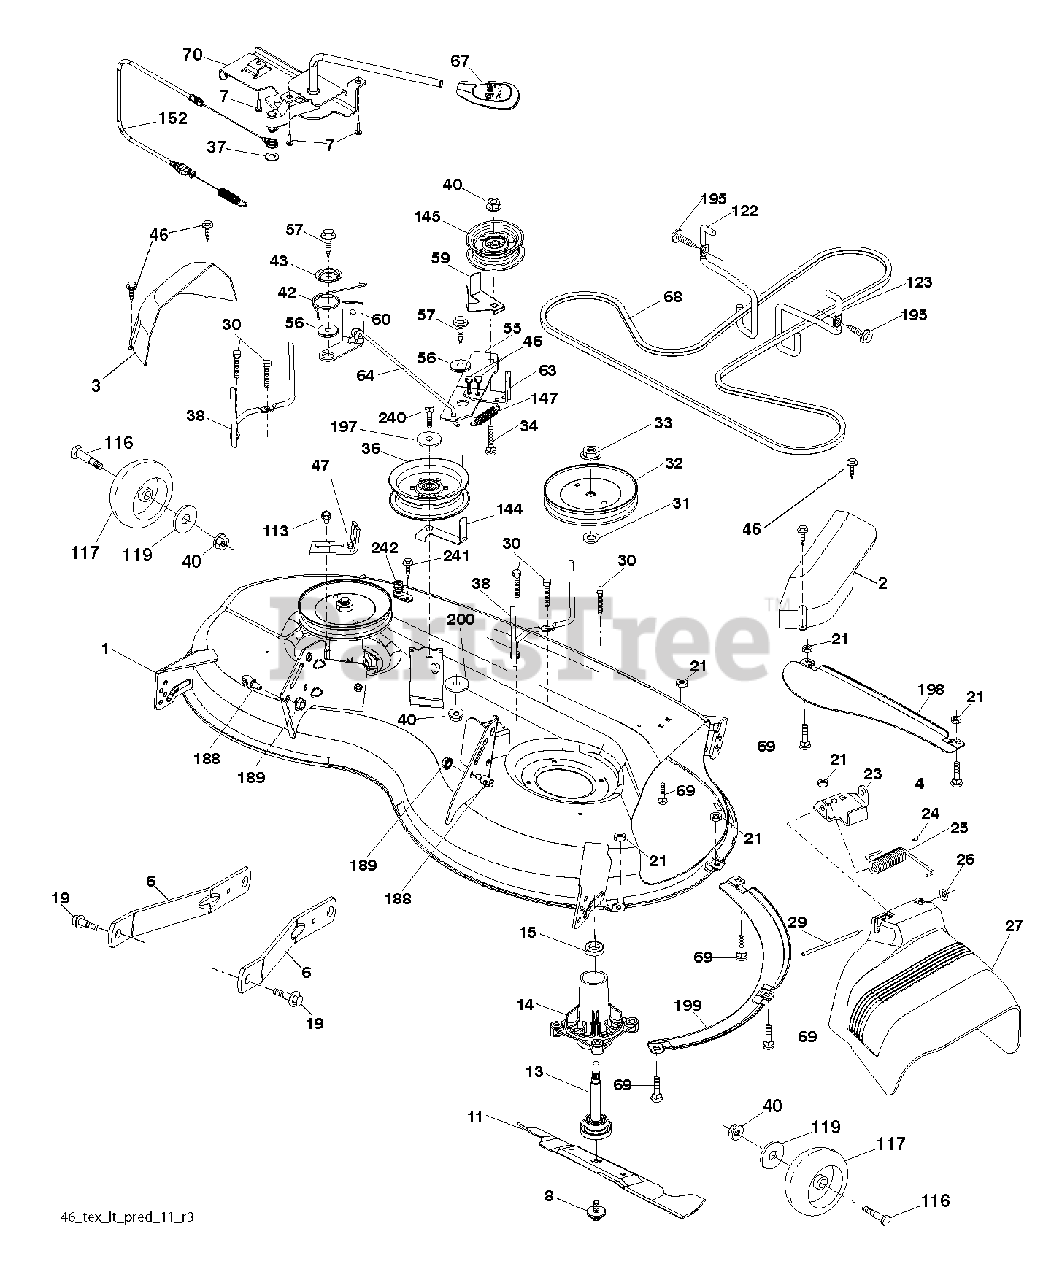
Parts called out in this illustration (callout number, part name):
1	DECK.WELDMENT.46.2GA.WHLS.GRAY
2	COVER.MANDREL.RH.46"
3	COVER.MANDREL.LH.46"
4	BOLT
6	ARM.SUSPENSION.MOWER.R
7	SCREW.#10 X 0.750.BOS
8	BOLT.WASHER.ASM.7/16-2
11	BLADE.MOWER.46".HI.LIFT
13	SHAFT.ASM.MDRL.N/GREASE.38
14	HOUSING.MANDREL.4PT.
19	BOLT.SHOULDER
21	LOCKNUT
23	BRKT.DEFLECTOR.38"2005+
24	CAP-SLEEVE LT
25	SPRING.TORSION.DEFLECT
26	NUT PUSH M
27	SHIELD.DEFLECTOR.MOWER.46"BLAC
29	ROD.HINGE
30	SCREW, WASHER HEAD
31	WASHER.SPACER.MANDREL
32	PULLEY.MANDREL.5.438.PD
33	NUT.FLANGE.LOCK.TOP
34	BOLT.3/8-16X1.50
36	PULLEY.IDLER.2006
37	WASHER
38	KEEPER.BELT.MANDREL.PULLEY
40	NUT LOCK FLG 3/8-16 UNC
42	SPRING.TORSION.BRAKE
43	SRPING.TORSION.RETAINE
46	SCREW.1/4-20X5/8
47	BRKT.CLUTCH.CABLE
56	SPACER.RETAINER
57	SCREW 3/8-16X1
59	GUARD, BELT
60	ARM BRAKE MOWER RH 38"
63	ARM BRAKE MOWER
64	LINKAGE BRAKE
67	HANDLE.CLUTCH.CABLE.LT
68	V-BELT
69	BOLT
70	CLUTCH.ASM.MANUAL.YT.PREDATORQ
113	BOLT.5/16HEX.WHS.HD
116	BOLT.SHOULDER.3/8-16X3-5/8.
117	WHEEL. GUAGE RALLY
119	WASHER
122	KEEPER BELT ENGINE LH
123	KEEPER BELT RH
144	KEEPER.BELT.MOWER
145	PULLEY.IDLER.48"PRIMARY
147	SPRING RETURN
152	CABLE.MECHANICAL.CLUTCH
188	STUD.FASTNER.W/ANTI-ROTATE
189	NUT LOCK HEX FLANGE 5/16-18
195	SCREW, 3/8-16X3/4
197	WASHER
198	BAFFLE CENTER FRONT
199	BAFFLE FRONT RH
200	WASHER.13/32 X 1 X 1/2.11GUARD
240	BOLT-HEX EAK
241	SCREW.TT.#10-32X.5.3/8.FLANGE
242	PORT.WASHOUT
